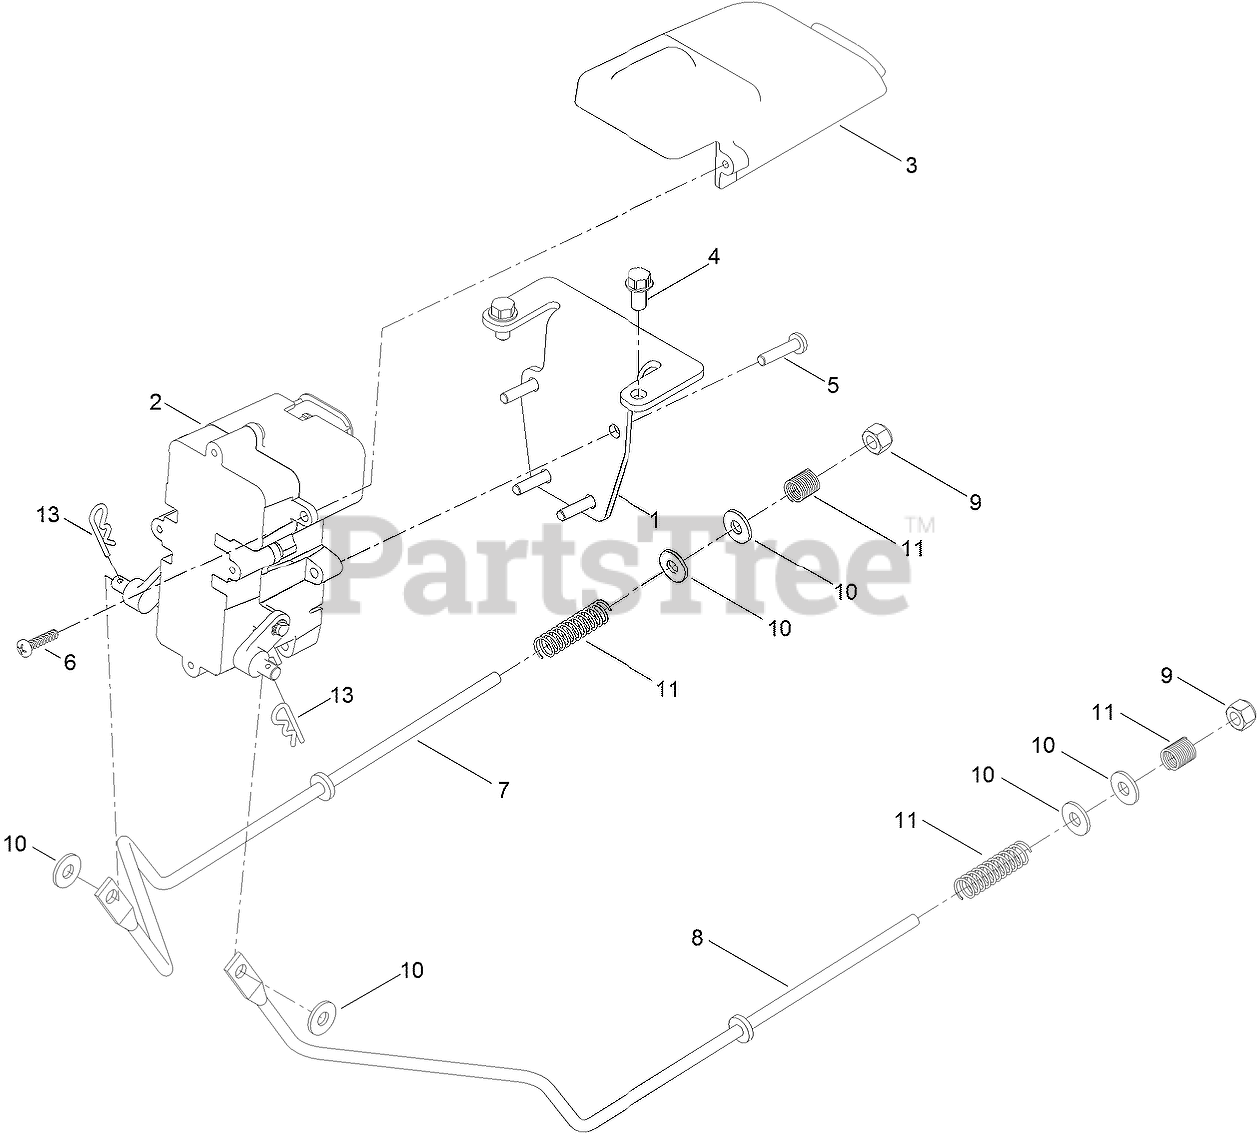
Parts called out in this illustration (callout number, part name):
1	BRACKET-MOUNT, BRAKE
2	BRAKE BOX ASM
3	COVER-CONNECTOR
4	SCREW-HWH
5	SCREW-PPH
6	SCREW-PPH
7	ROD-BRAKE, WIDE (RH)
8	ROD-BRAKE, WIDE (LH)
9	NUT-HEX
10	WASHER
11	SPRING-COMPRESSION
13	PIN-HAIR
